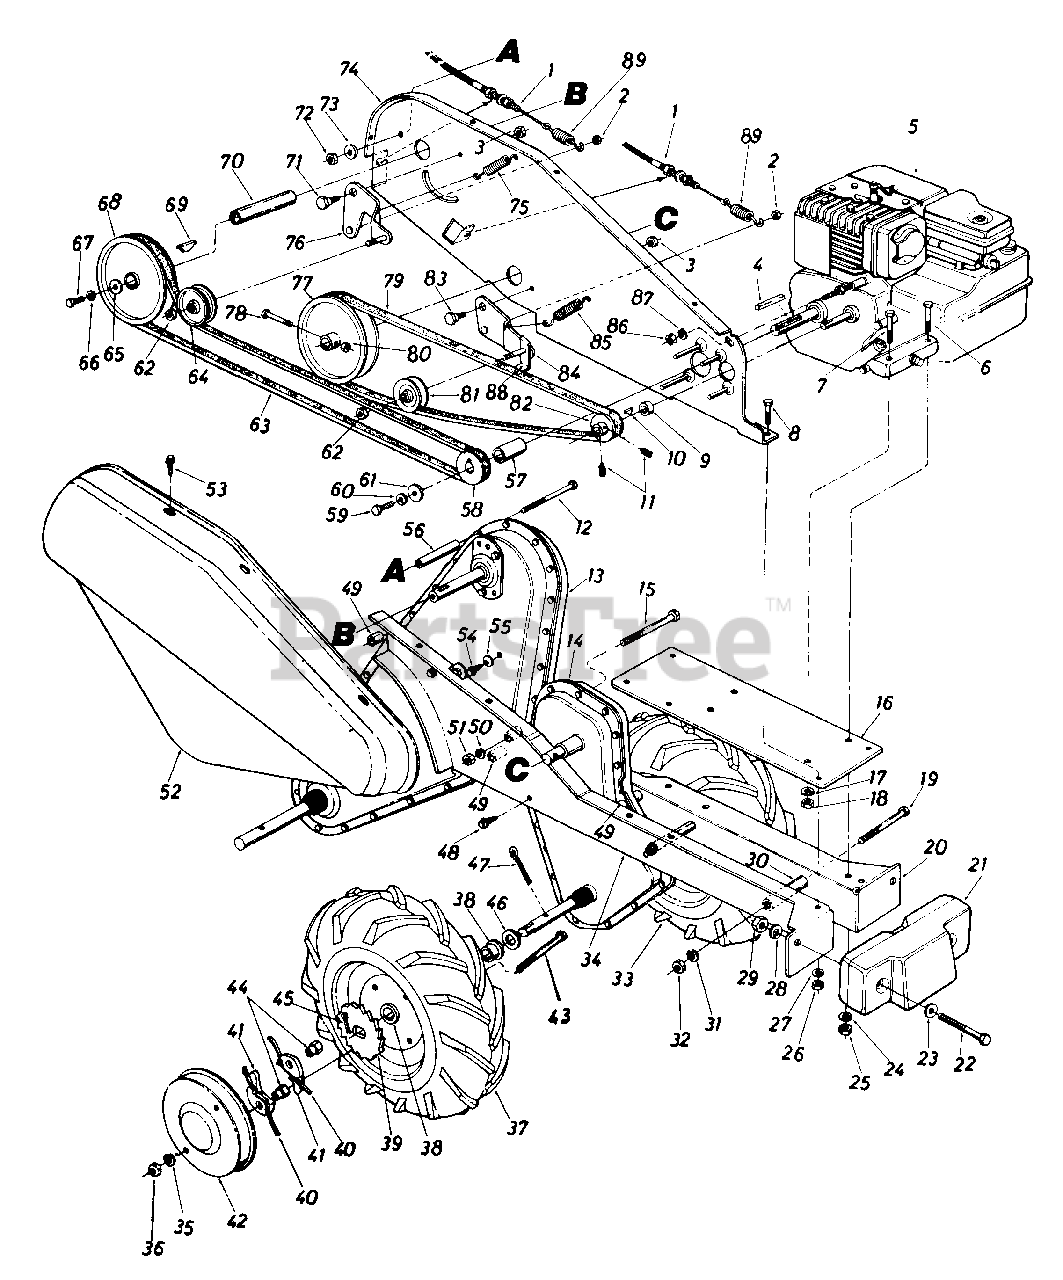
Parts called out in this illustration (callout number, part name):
1	Clutch Control Cable
2	Hex Cent. L-Nut 1/4-20 Thd.
3	Hex Cent. L-Nut 3/8-16 Thd.
4	Sq. Key 3/16" Dia. x .75
5	Engine
6	Hex Bolt 5/16-18 x 1.50" Lg.
7	Hex Bolt 5/16-18 x 1.50" Lg.
8	Hex Bolt 5/16-18 x .75" Lg.
9	Spacer .51" I.D. x 3/4" O.D. x .39" Lg.
10	Hi-Pro Key #5 Woodruff
11	Set Scr. 1/4-28 x .25" Lg.
12	Hex Bolt 5/16-18 x 3.0" Lg.
15	Hex Bolt 5/16-18 x 3.0" Lg.
18	Hex Nut 5/16-18 Thd.
19	Hex Bolt 3/8-24 x 3.0" Lg.
22	Hex Bolt 1/2-13 x 4.0" Lg.
23	Fl-Wash. 1/2" I.D. x 1.0" O.D.
24	L-Wash. 5/16" I.D.
25	Hex Nut 5/16-18 Thd.
26	Hex Nut 5/16-18 Thd.
27	L-Wash. 5/16" I.D.
28	L-Wash. 1/2" I.D.
29	Hex Nut 1/2-13 Thd.
30	Spacer 3/8" I.D. x 5/8" O.D. x 2.18" Lg.
31	L-Wash. 3/8" I.D.
32	Hex Nut 3/8-24 Thd.
33	Comp. Wheel Ass'y. - L.H.
36	L-Wash. 5/16" I.D.
37	Comp. Wheel Ass'y. - R.H.
38	Flange Brg. 7/8" I.D. x 1.12" Lg.
39	Ratchet Wheel
40	Nylon Spring
41	Pawl .44" I.D.
42	Wheel Cover
43	Hex Bolt 5/16-24 x 1.25" Lg.
44	Special Hex Nut 5/16-24 Thd.
45	Cotter Pin 1/8" Dia. x 1.25" Lg.
46	Fl-Wash. 7/8" I.D. x 1-3/8" O.D. x .06
47	Cotter Pin 1/8" Dia. x 1.25" Lg.
48	Hex Wash. Self-Tap Scr. 5/16-24 x .50" Lg.
49	Spacer 5/16" I.D. x 16 Ga. x .96" Lg.
50	L-Wash. 5/16" I.D.
51	Hex Nut 5/16-18 Thd.
52	Belt Cover
53	Hex Wash. S-Tap Scr. 1/4-20 x .50" Lg.
54	Hex Wash. S-Tap Scr. 1/4-20 x 3/8" Lg.
55	Bell-Wash. 1/4" I.D.
56	Spacer 3/8" I.D. x 1/2" O.D. x 2.0" Lg.
57	Spacer 3/4" I.D. x 1.12" O.D. x 1.56" Lg.
58	1/2" "V"-4L Pulley 3/4" I.D. x 2.59" O.D.
59	Hex Bolt 5/16-24 x 1.00" Lg.
60	L-Wash. 5/16" I.D.
61	Fl-Wash. 5/16" I.D. x 1.25" O.D.
62	Hex L-Nut 3/8-24 Thd.
63	"V"-Belt 1/2" x 54" Lg. 54" Lg.
64	Fl-Idler Pulley 3.75" O.D. x 3/8" I.D.
65	Fl-Wash. .25" I.D. x .93" O.D. x .120
66	L-Wash. 1/4" I.D.
67	Hex Bolt 1/4-28 x .75" Lg.
68	Split Pulley 6" Dia.
69	Hi-Pro Key
71	Shld. Bolt 1/2" Dia. x .210" Lg.
72	Hex Nut 5/16-18 Thd.
73	Bell-Wash. 5/16" I.D.
74	Side Plate Ass'y.
75	Ext. Spring .50" O.D. x 1.55" Lg.
76	Idler Bracket Ass'y. - Tines
77	Pulley 6" Dia. x 5/8" I.D.
78	Hex Bolt 1/4-28 x 1.50" Lg.
79	"V"-Belt 1/2" x 43" Lg.
80	Hex Cent. L-Nut 1/4-28 Thd.
81	"V"-Idler Pulley 2-5/8" O.D.
82	1/2" "V"-Pulley 2 1/4" O.D. x .50" I.D.
83	Shld. Bolt 1/2" Dia. x .160" Lg.
84	Idler Bracket Ass'y. - Wheels
85	Ext. Spring .50" O.D. x 1.97" Lg.
86	Hex Nut 1/4-20 Thd.
87	L-Wash. 1/4" I.D.
88	Belt Keeper Ass'y.
89	Ext. Spring
